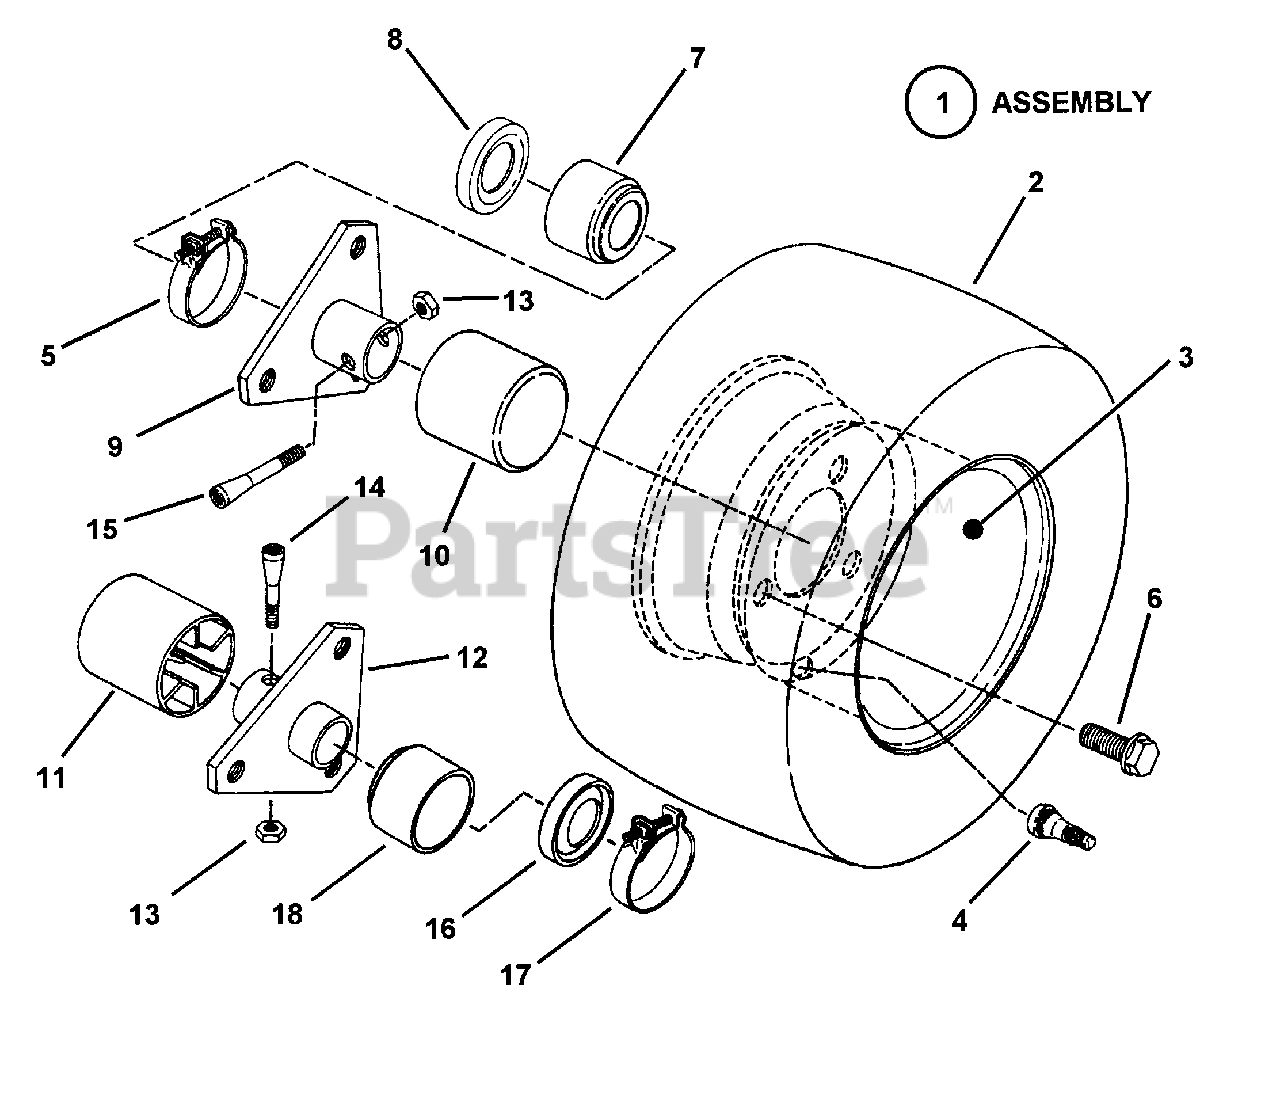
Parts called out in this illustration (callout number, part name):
1	ASSEMBLY, Rear Tire & Rim
2	TIRE, Ext. Wide, 16/7.50 x 8
3	RIM, Ext. Wide
4	VALVE, Air (Snap-in)
5	CLAMP, Right Hand
6	BOLT, 1/2-20 x 3/4" Lug (Grade 5)
7	BOOT, Right Hand (.940" hole)
8	SEAL, Oil
9	HUB, Rear Wheel (Right Hand)
10	CAP, Hub
11	CAP, Hub (Left Hand)
12	HUB, Rear Wheel
13	NUT, 5/16-24 Hex Center Lock
14	BOLT, 5/16-24 x 1-5/8" Tapered (Left Hand)
15	BOLT, 5/16-24 x 2" Tapered (Right Hand)
16	SEAL, Oil (Left Hand)
17	CLAMP, (Left Hand)
18	BOOT, (Left Hand)(3/4" hole)
